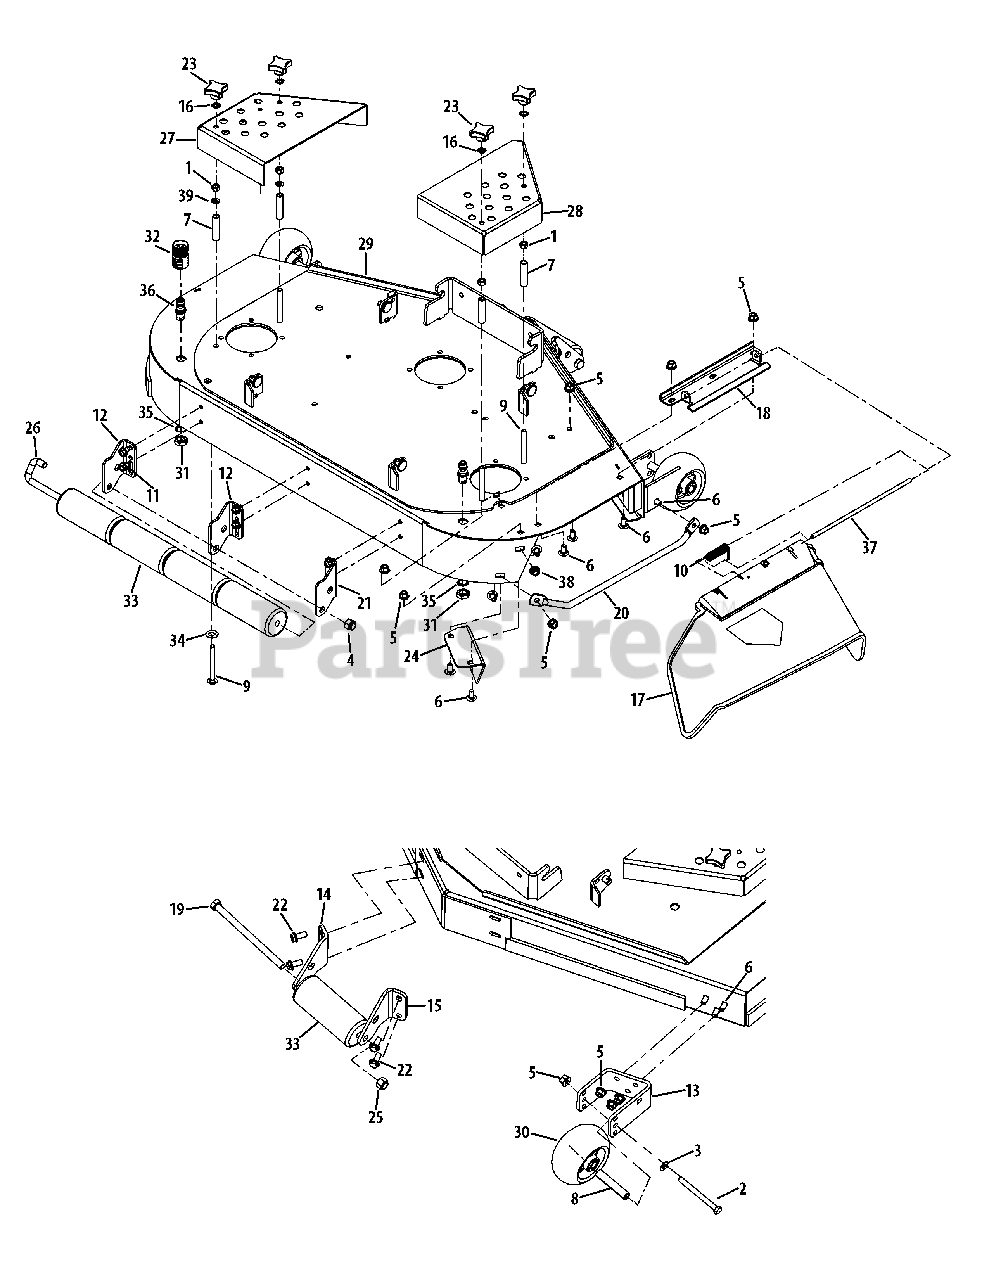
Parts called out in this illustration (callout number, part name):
1	Nut, 3/8-16
2	Hex Screw, 3/8-16 x 4.00
3	Washer, .406 x .813 x .063
4	Hex Lock Nut, 1/2-13
5	Flange Counter Lock Nut, 3/8-16
6	Carriage Bolt, 3/8-16 x .75
7	Spacer, .400 x .560 x 2.45
8	Spacer, .390 x .620 x 3.04
9	Carriage Bolt, 3/8-16 x 3.50
10	Torsion Spring, .639 x 2.16 x .12
11	Flange Screw, 3/8-16 x .500
12	Roller Mount Bracket
13	Anit-Scalp Front Mount Bracket
14	LH Front Roller Mount Bracket
15	RH Front Roller Mount Bracket
16	Washer, .398 x .694 x .032
17	Chute Deflector
18	Chute Deflector Bracket
19	Hex Screw, 1/2-20 x 7.50
20	Finger Guard
21	RH Roller Mt. Bracket
22	Flange Screw, 3/8-16 x .875
23	Plastic Knob, 3/8-16
24	Micro Chute Baffle
25	Nut, 1/2-20
26	J-Hook
27	LH Belt Cover
28	RH Belt Cover
29	Deck Assembly
30	Wheel
31	Hex Nut
32	Water Nozzle Adapter
33	Front Roller
34	Flat Washer, .510 x 1.00 x .060
35	Lock Washer, 17 x 23.8 x 1.95
36	Water Deck Nozzle
37	Chute Deflector Rod
38	Nut, Flange Lock, 3/8-16
39	Lock Washer, 3/8
